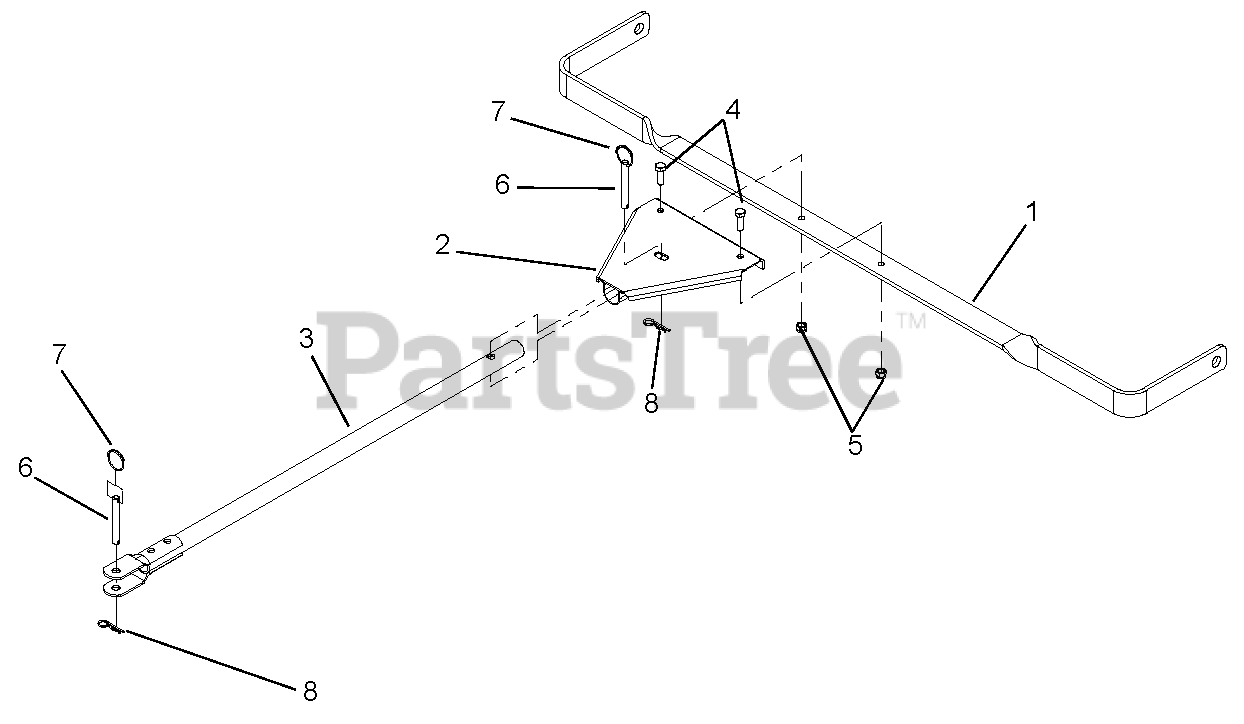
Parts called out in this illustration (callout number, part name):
2	Hitch Plate Weldment
3	Tounge Weldment
4	Bolt, 5/16-18 x 1 Hex 5
5	Nut, 5/16-18 Nyloc
6	Pin, Hitch
7	Ring, Retaining
8	Pin, Cotter, .09 x 1.50
